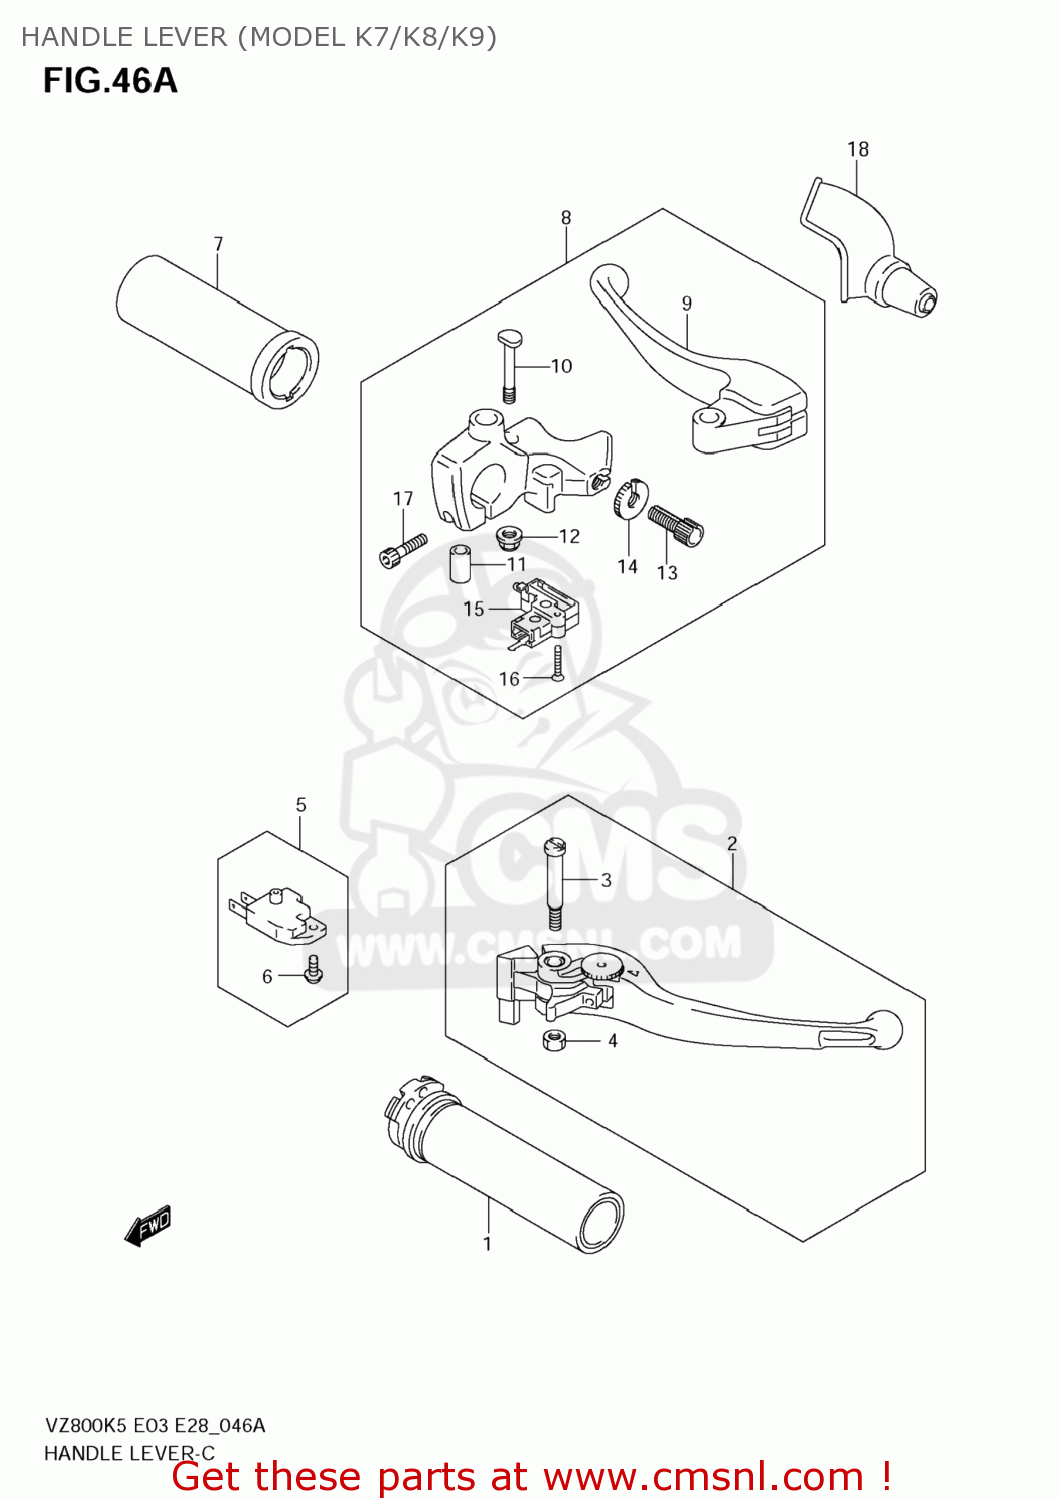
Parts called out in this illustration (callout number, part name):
1	GRIP,THROTTLE
2	LEVER ASSY,BRAKE
3	BOLT,PIVOT
4	NUT
5	SWITCH ASSY,ST
6	SCREW
7	GRIP,L
8	LEVER ASSY,CLU
9	LEVER,CLUTCH
10	BOLT,LEVER PIVOT
11	COLLAR
12	NUT
13	ADJUSTER,WIRE
14	NUT,LOCK
15	SWITCH,CLUTCH
16	SCREW
17	BOLT
18	COVER,CLUTCH LEVER
